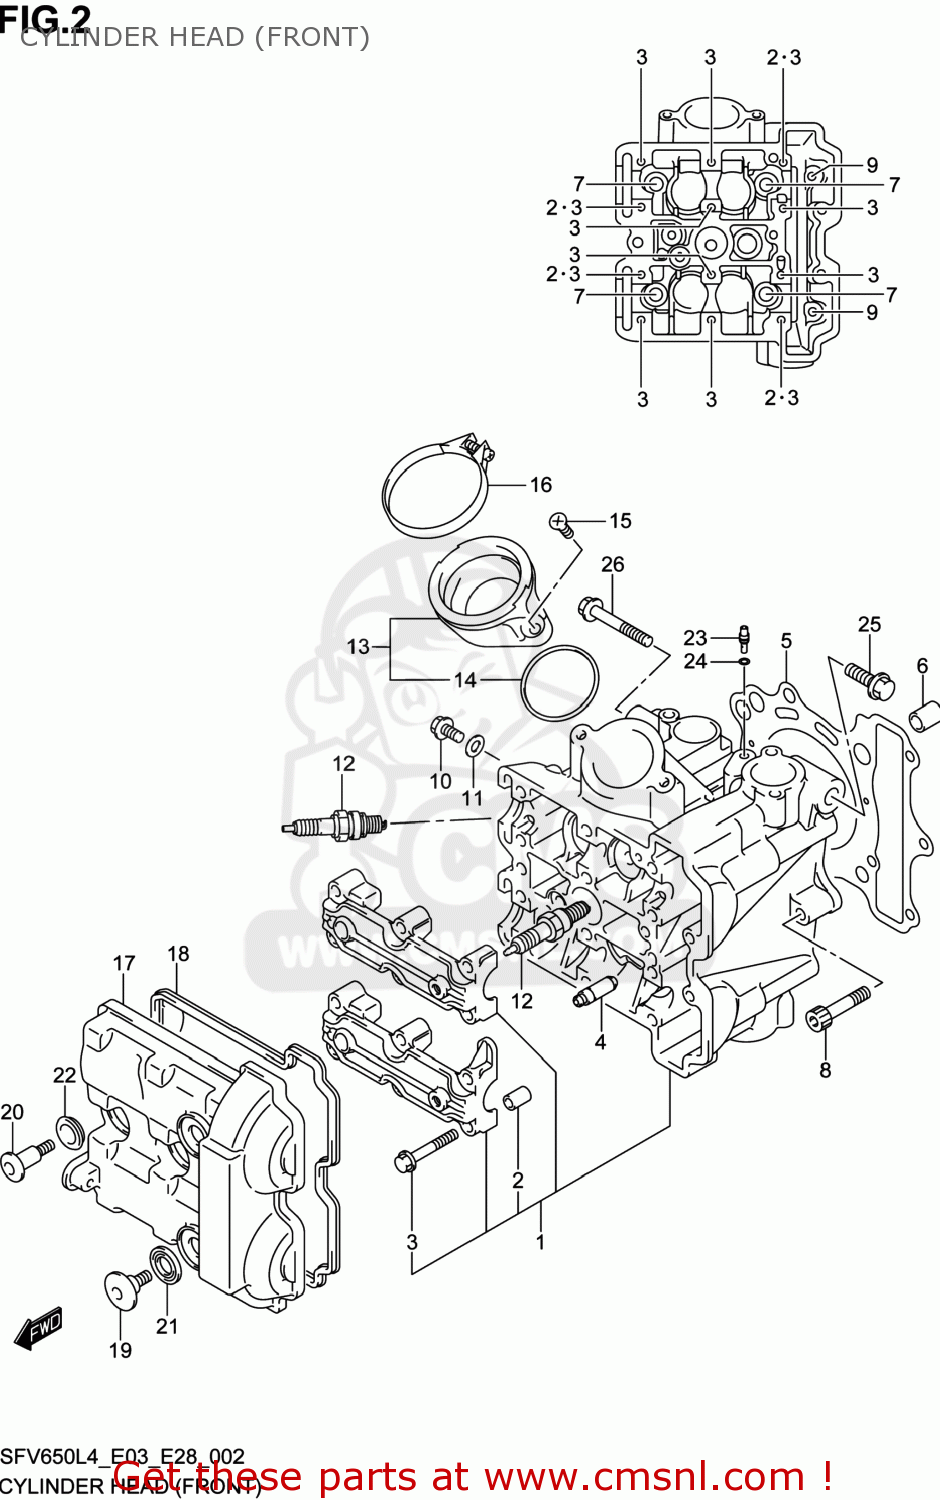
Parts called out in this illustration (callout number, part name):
1	HEAD ASSY,CYLINDER FR
2	PIN(6.2X8X11)
3	BOLT(6X40)
4	GUIDE,VALVE
5	GASKET,CYLINDER HEAD (NAS)
6	PIN
7	BOLT,CYLINDER HEAD(L:160)
8	BOLT
9	BOLT(6X70)
10	BOLT(6X12)
11	GASKET(5.8X13X1.2) (NAS)
12	PLUG,SPARK(IU24D)
13	PIPE ASSY,INTAKE FR
14	O RING(D:2.4,ID:47X42)
15	SCREW
16	CLAMP,INTAKE PIPE
17	COVER,CYLINDER HEAD FR
18	GASKET,CYLINDER HEAD COVER (NAS)
19	BOLT(7X17.5)
20	BOLT(7X31)
21	WASHER,CYL HEAD COVER
22	CUSHION,HEAD COVER BOLT
23	JET(8)
24	O RING(D:1.2,ID:4)
25	BOLT(10X25)
26	BOLT
